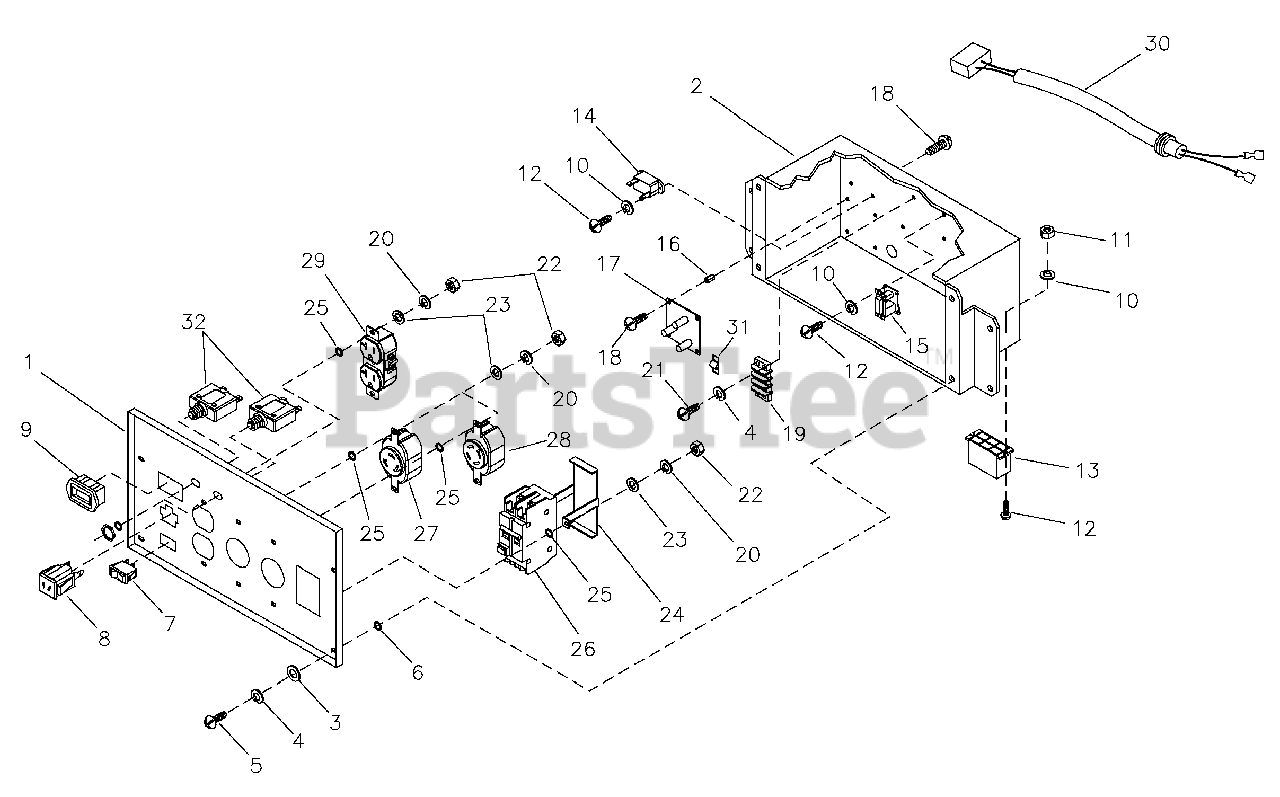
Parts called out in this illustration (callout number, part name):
2	BOX, Control Panel
3	*WASHER, Flat, #10 - M5
4	*LOCKWASHER, M5
5	*SCREW, Phillips Head, M5 - 0.8 x 12
6	*WASHER, Shakeproof, INT., M6-1/4
7	SWITCH, ON/OFF
10	*LOCKWASHER, M3
11	*NUT, M3-1/2
12	*SCREW, Phillips Head, M3 - 1/2 x 10
14	BREAKER, Circuit, 10A
17	BOARD, Idle Control
18	*SCREW, Phillips Pan Head, Self Tapping, #6-32 x 3/8
19	STRIP, Terminal
20	*LOCKWASHER, M4
21	*SCREW, Phillips Head, M5 - 0.8 x 20
22	*NUT, M4 - 0.7
23	*WASHER, Flat, M4
25	*WASHER, Shakeproof, INT. #8
26	BREAKER, Circuit, 30A
27	OUTLET, 120V TL30A
28	OUTLET, 120/240V TL30A
29	OUTLET, 120V 20A
30	HARNESS, Wiring
31	BLOCK, Terminal
32	BREAKER, Circuit, 20A
